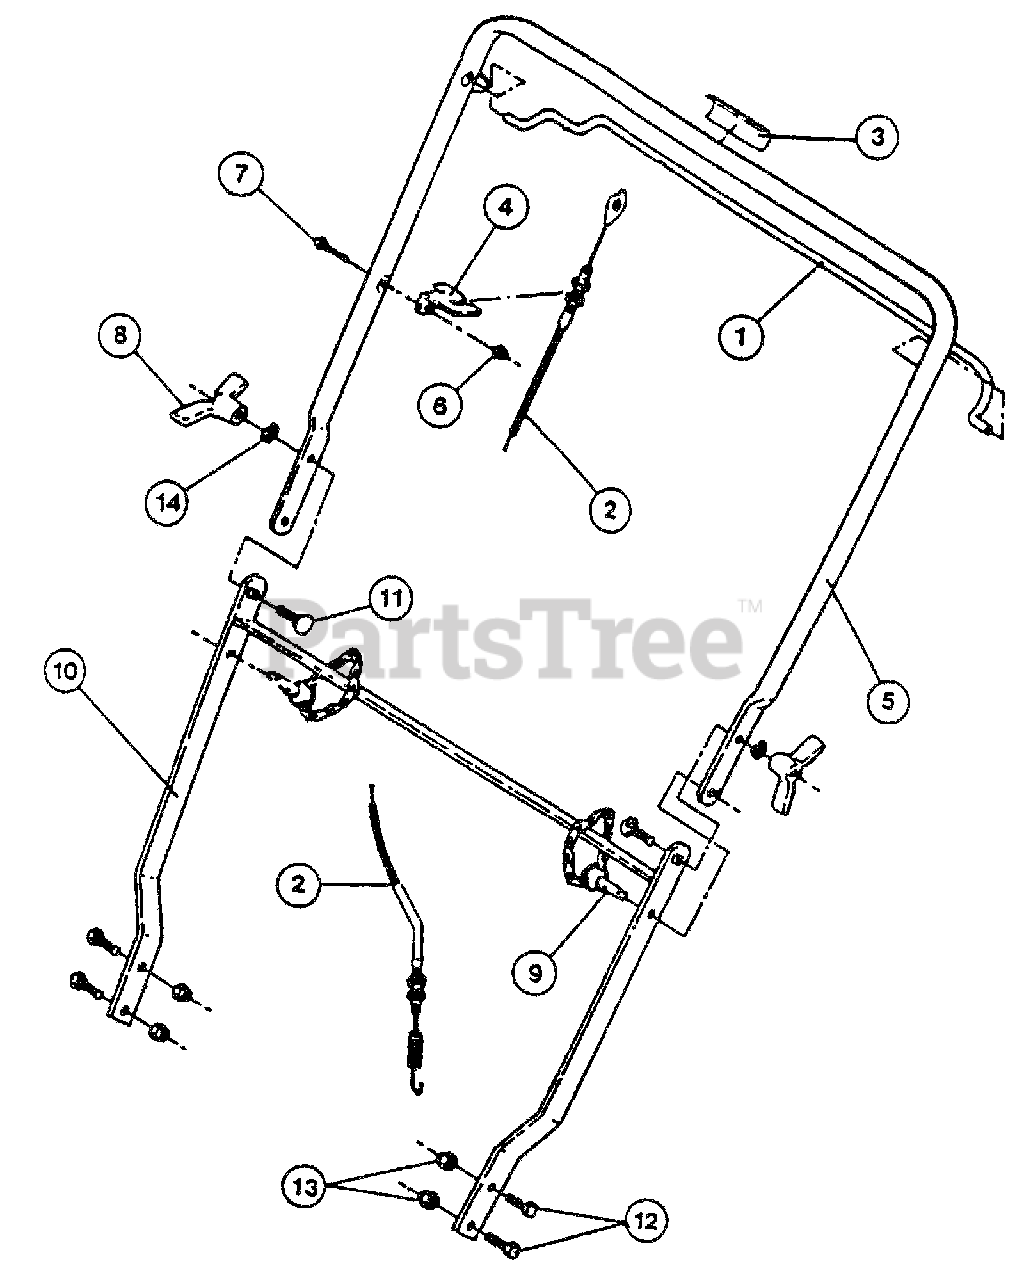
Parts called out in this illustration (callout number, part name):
1	Clutch Bail
2	Clutch Cable
3	Clutch Control Decal
4	Cable Mounting Bracket
5	Upper Handle
6	1/4-20 Nyloc Nut
7	1/4-20 x 1-1/2 Hex Cap Screw
9	Detent Pin Assembly
10	Lower Handle
11	5/16-18 x 1-1/4 Carriage Bolt
12	3/8-16 x 1 Hex Cap Screw
13	3/8-16 Nyloc Nut
14	5/16 Split Lock Washer
